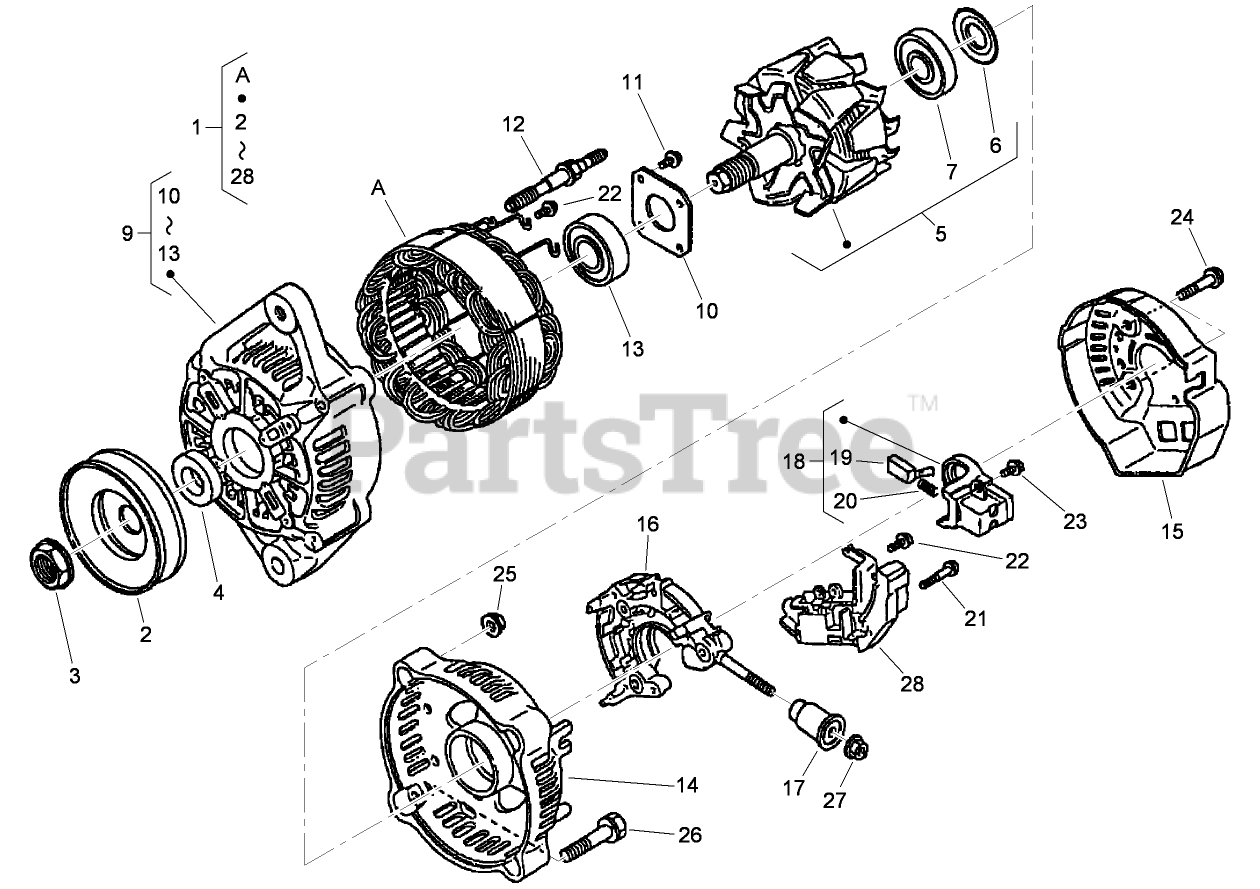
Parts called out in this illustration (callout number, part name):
1	60 AMP ALTERNATOR ASM
2	PULLEY-DYNAMO
4	COLLAR
5	ROTOR ASM
6	COVER-BEARING
7	Bearing-Ball
9	DRIVE END FRAME ASM
10	PLATE-RETAINER
11	SCREW-HEAD, ROUND
12	BOLT-THROUGH
13	Bearing-Ball
14	FRAME-END
15	COVER-END
16	HOLDER
17	INSULATION-BRUSH
18	Brush Holder ASM
19	BRUSH
20	SPRING-BRUSH
21	SCREW-HEAD, ROUND
22	SCREW-HEAD, ROUND
23	SCREW-HEAD, ROUND
28	REGULATOR ASM
